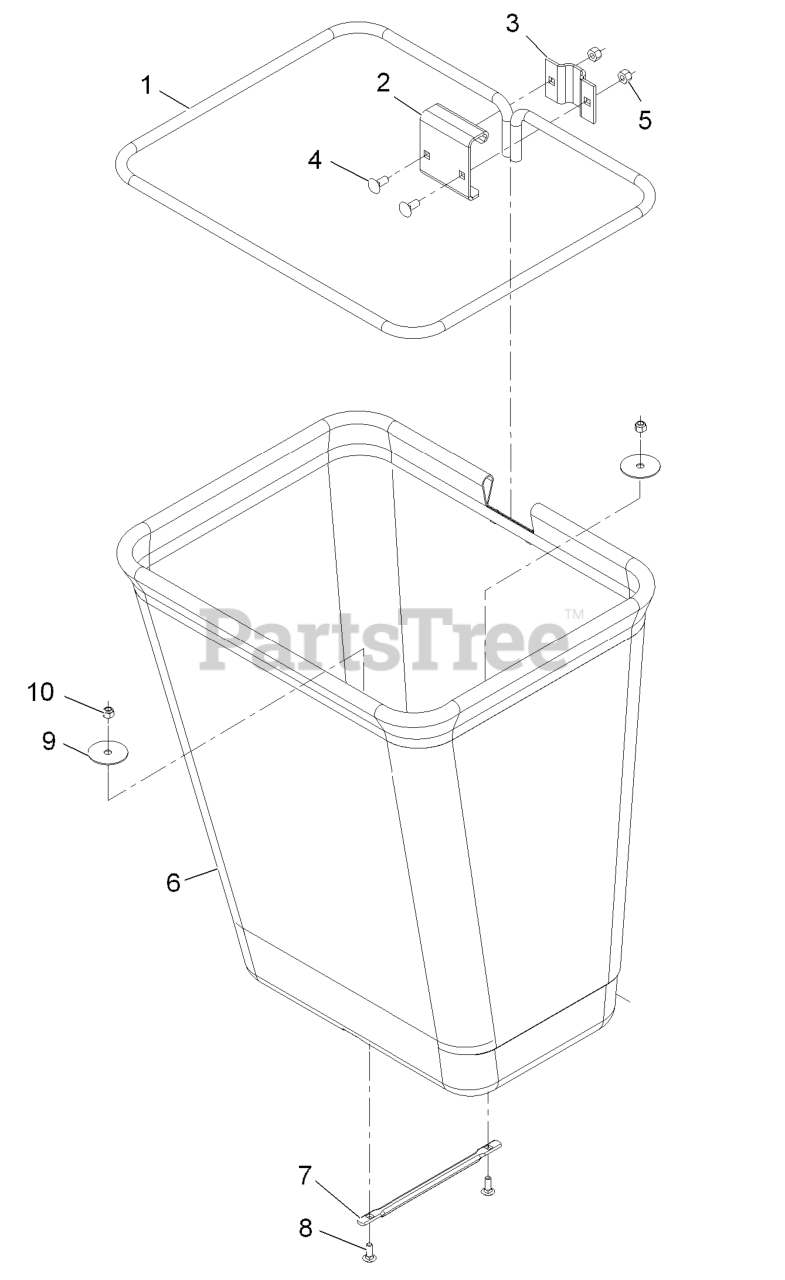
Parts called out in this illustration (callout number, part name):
1	Frame-Bag
2	Hanger-Bag
4	Bolt-Carriage 5/16-18 X 3/4
5	Nut-Nyloc 5/16-18
6	Bag ASM
7	Handle-Bag
8	Bolt-Carriage 1/4-20 X 3/4
10	Nut-Nyloc 1/4-20
